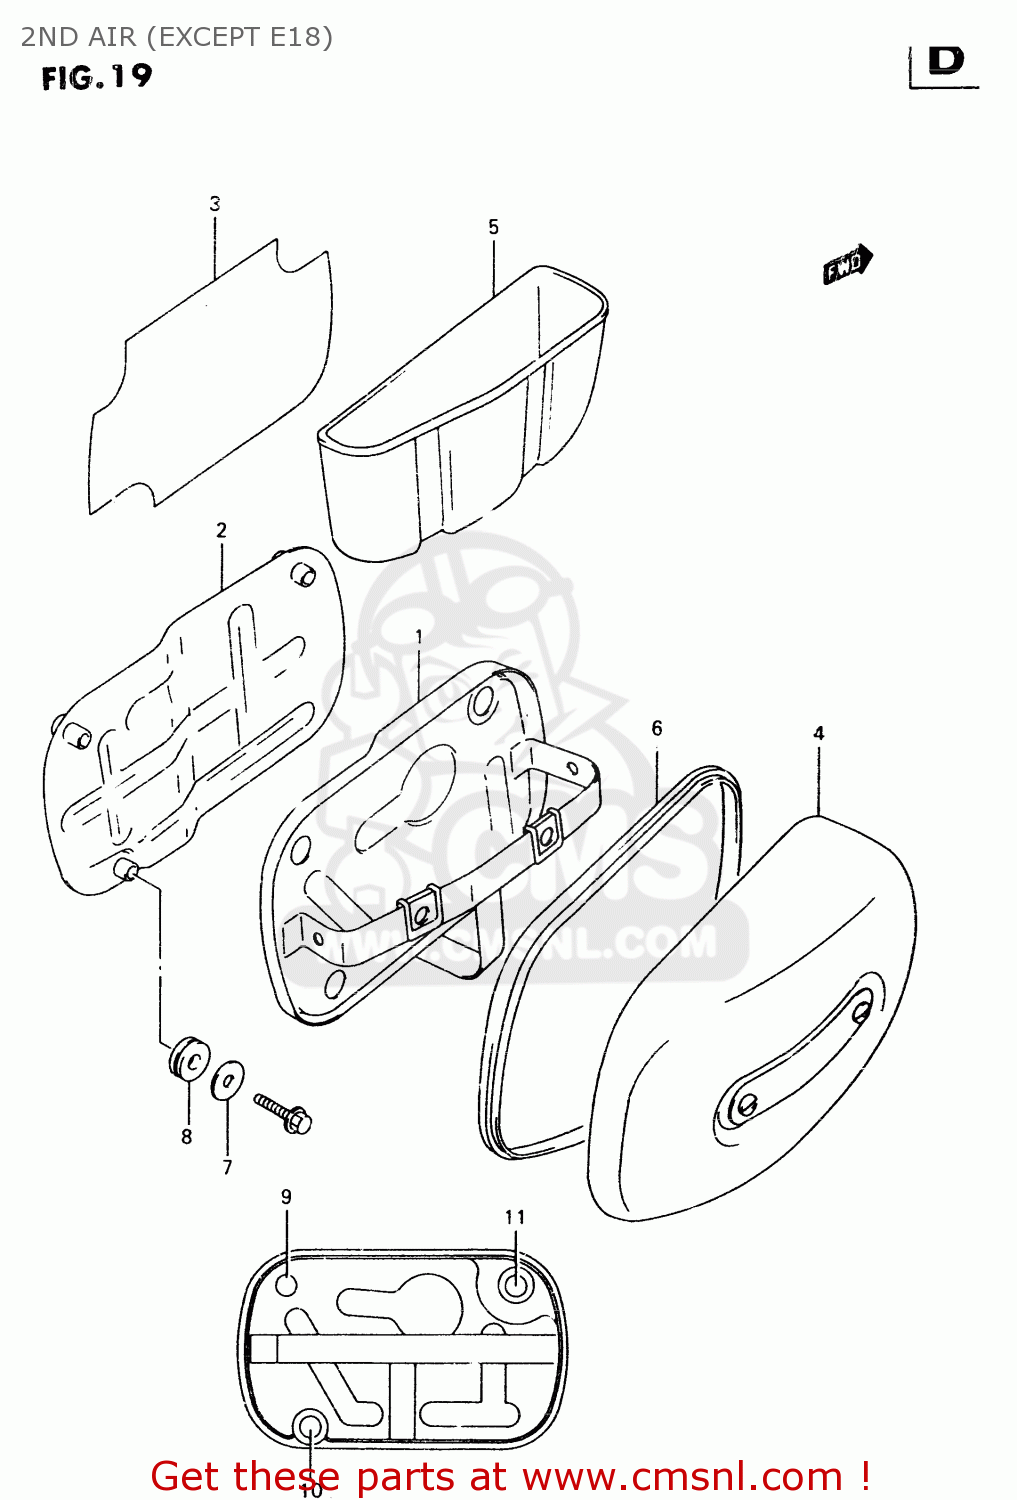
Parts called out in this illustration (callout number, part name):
1	BRACKET,2ND AIR SPRT
2	PLATE
3	SHEET,2ND AIR HEAT GUARD PLATE
4	COVER,2ND AIR
5	HOLDER,2ND AIR
6	CUSHION
7	WASHER
8	CUSHION
9	BOLT
10	BOLT
11	BOLT
